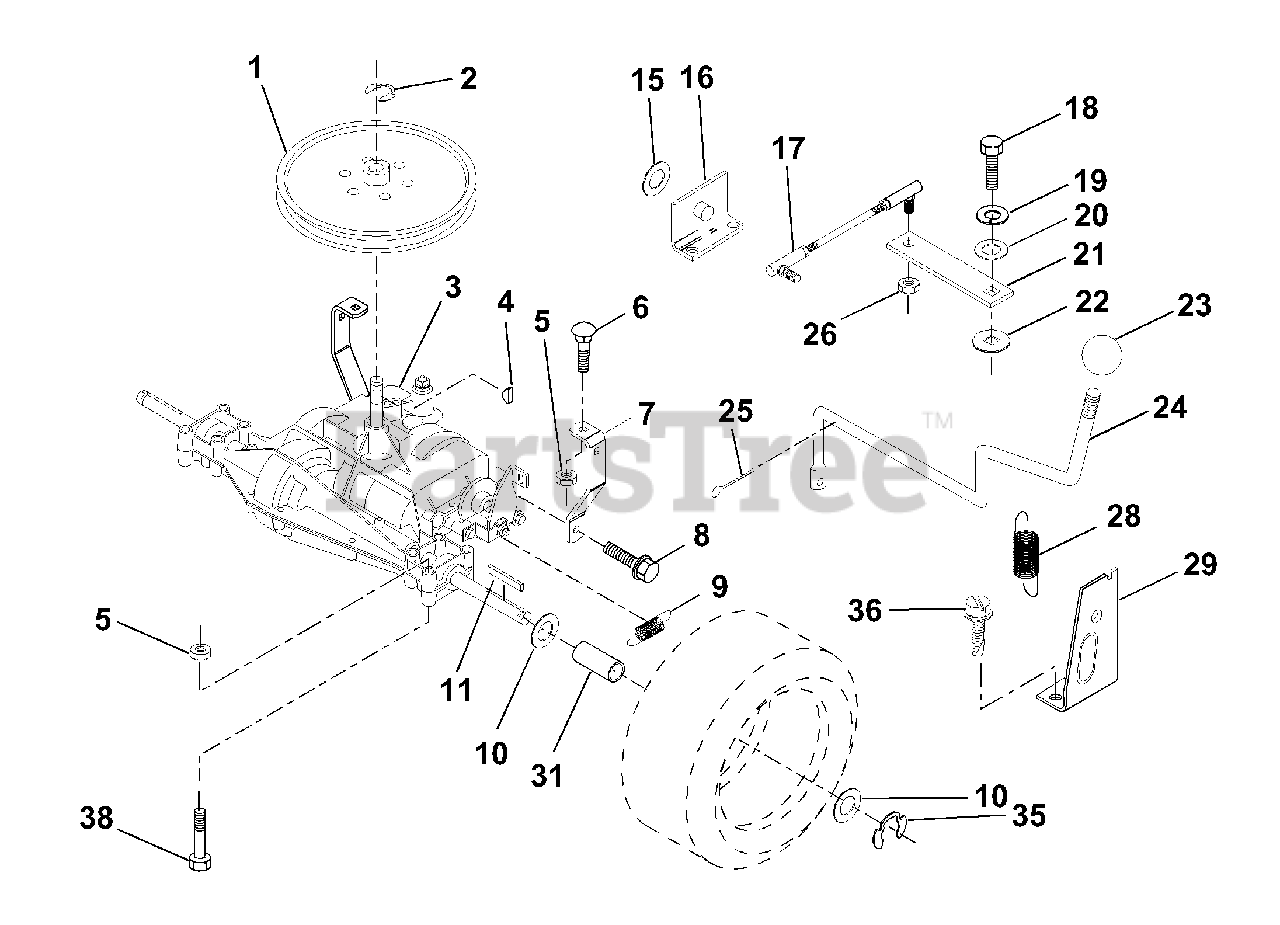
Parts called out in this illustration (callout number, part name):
2	Ring, Retainer
3	Transaxle, Peerless
4	Key, Woodruff #9
5	Nut, Crownlock 5/16-18
6	Bolt, Carriage 5/16-18 UNC x 3/4
7	Strap, Torque
8	Screw 5/16-18 x 3/4
9	Spring, Brake
10	Washer 25/32 x 1-1/4 x 16 Ga.
11	Key, Square
15	Washer 17/32 x 1 x 16 Ga.
16	Support Handle Shift LH
17	Link, Shift
18	Bolt, Fin Hex 1/4-28 UNF x 3/4 Gr. 8
19	Washer, Lock 1/4
20	Washer 9/32 x 3/4 x 10 Ga.
21	Arm, Shift
22	Washer, Shift Plate
23	Knob, Rd 1/2-13
25	Pin, Cotter 1/8 x 1
26	Locknut 5/16-24 UNF
28	Extension, Spring
29	Support Handle Shift RH
31	Spacer Axle
36	Screw, Thd Cut 1/4-20 x 1/2
38	Bolt Hex Flghd 5/16-18 x Gr. 5
